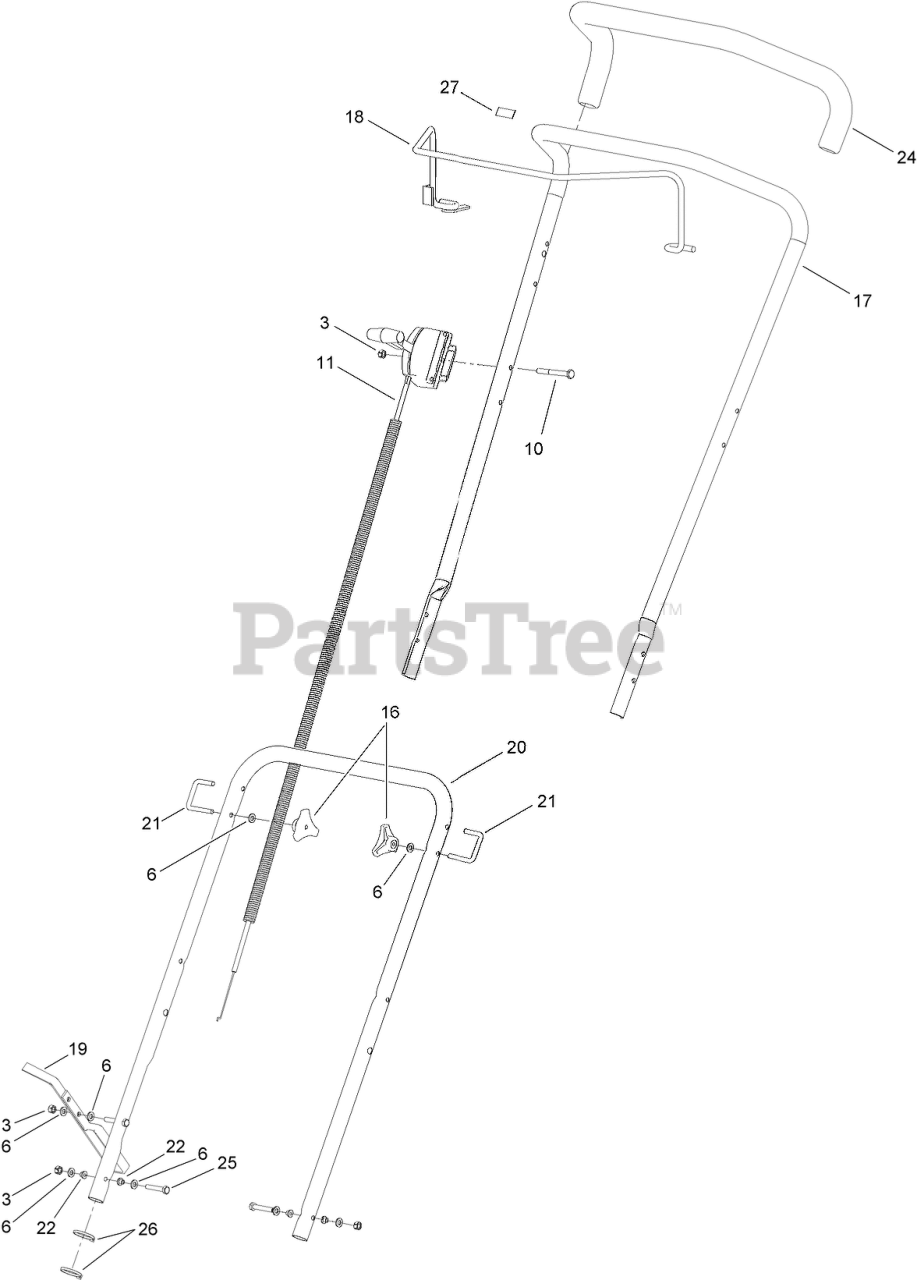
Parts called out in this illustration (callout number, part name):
3	NUT-NYLOC
6	WASHER
10	SETSCREW
11	THROTTLE CONTROL WITH OPC ASM
16	HANDWHEEL
17	HANDLE-UPPER
18	ARM-BAIL
19	FOOTSTOP
20	HANDLE-LOWER
21	BOLT-U
22	SPACER-HANDLE
24	GRIP-HANDLE
25	BOLT-HEX
26	TIE-CABLE
27	DECAL-STOP
